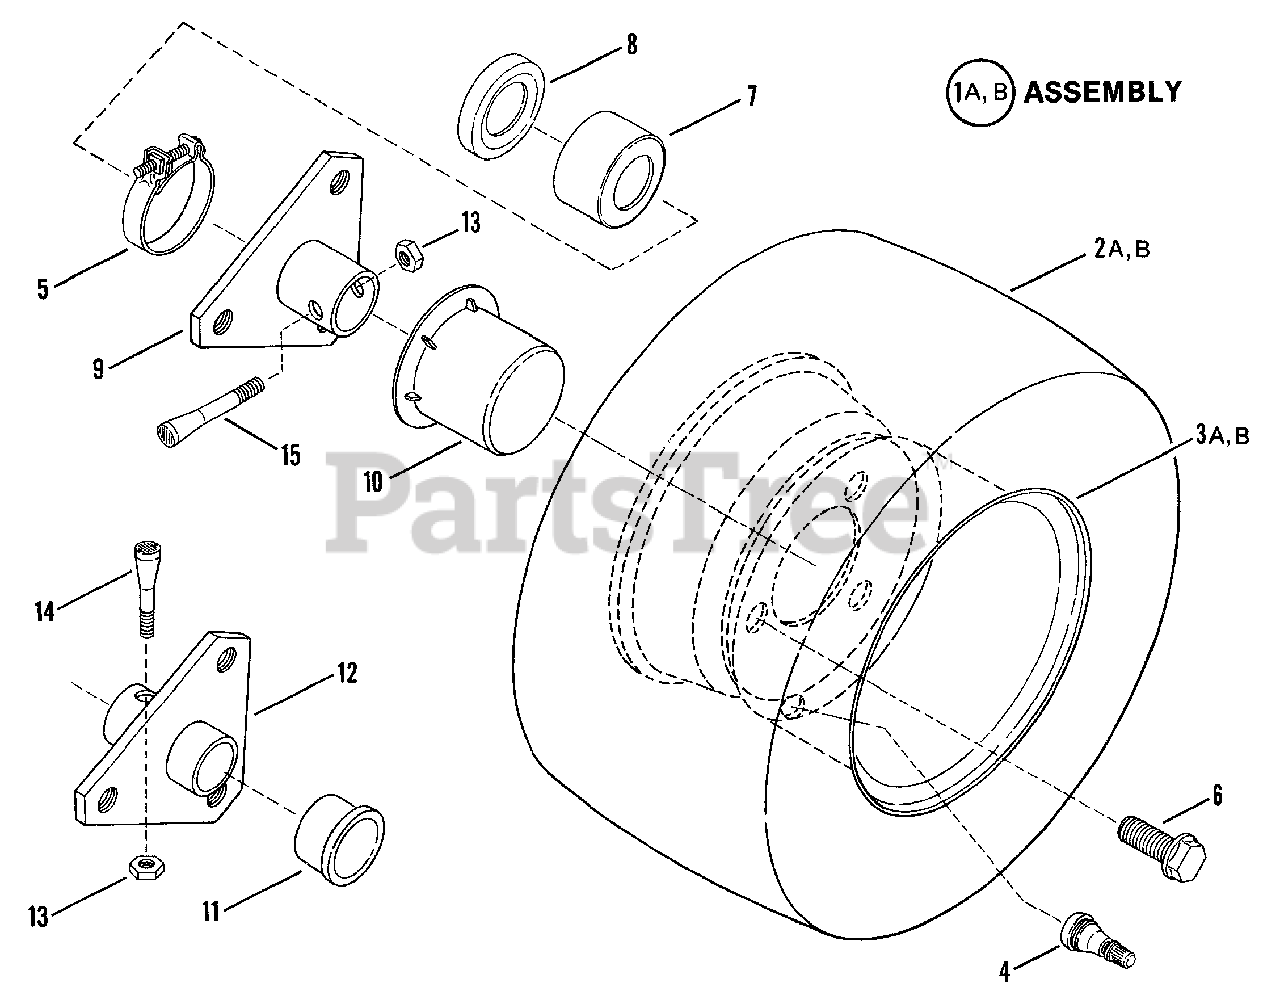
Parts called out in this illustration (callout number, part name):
1A	ASSEMBLY, Rear Tire & Rim
1B	ASSEMBLY, Rear Tire & Rim
2A	TIRE, 16 x 4.80 - 8
2B	TIRE, Wide, 16/6.50x8
3A	RIM, Std.,
3B	RIM, Wide,
4	VALVE, Air (Snap-in)
5	CLAMP
6	BOLT, 1/2-20x3/4" Lug
7	CAP, Seal, Right Hand
8	SEAL, Oil
9	HUB, Rear Wheel, Right Hand
10	HUB-CAP
11	CAP, Seal L.H. 3/4"
12	HUB, Rear Wheel, Left Hand
13	NUT, 5/16-24 Lock
14	BOLT, 5/16-24x1-5/8", Tapered, Left Hand
15	BOLT, 5/16-24x2", Tapered, Right Hand
